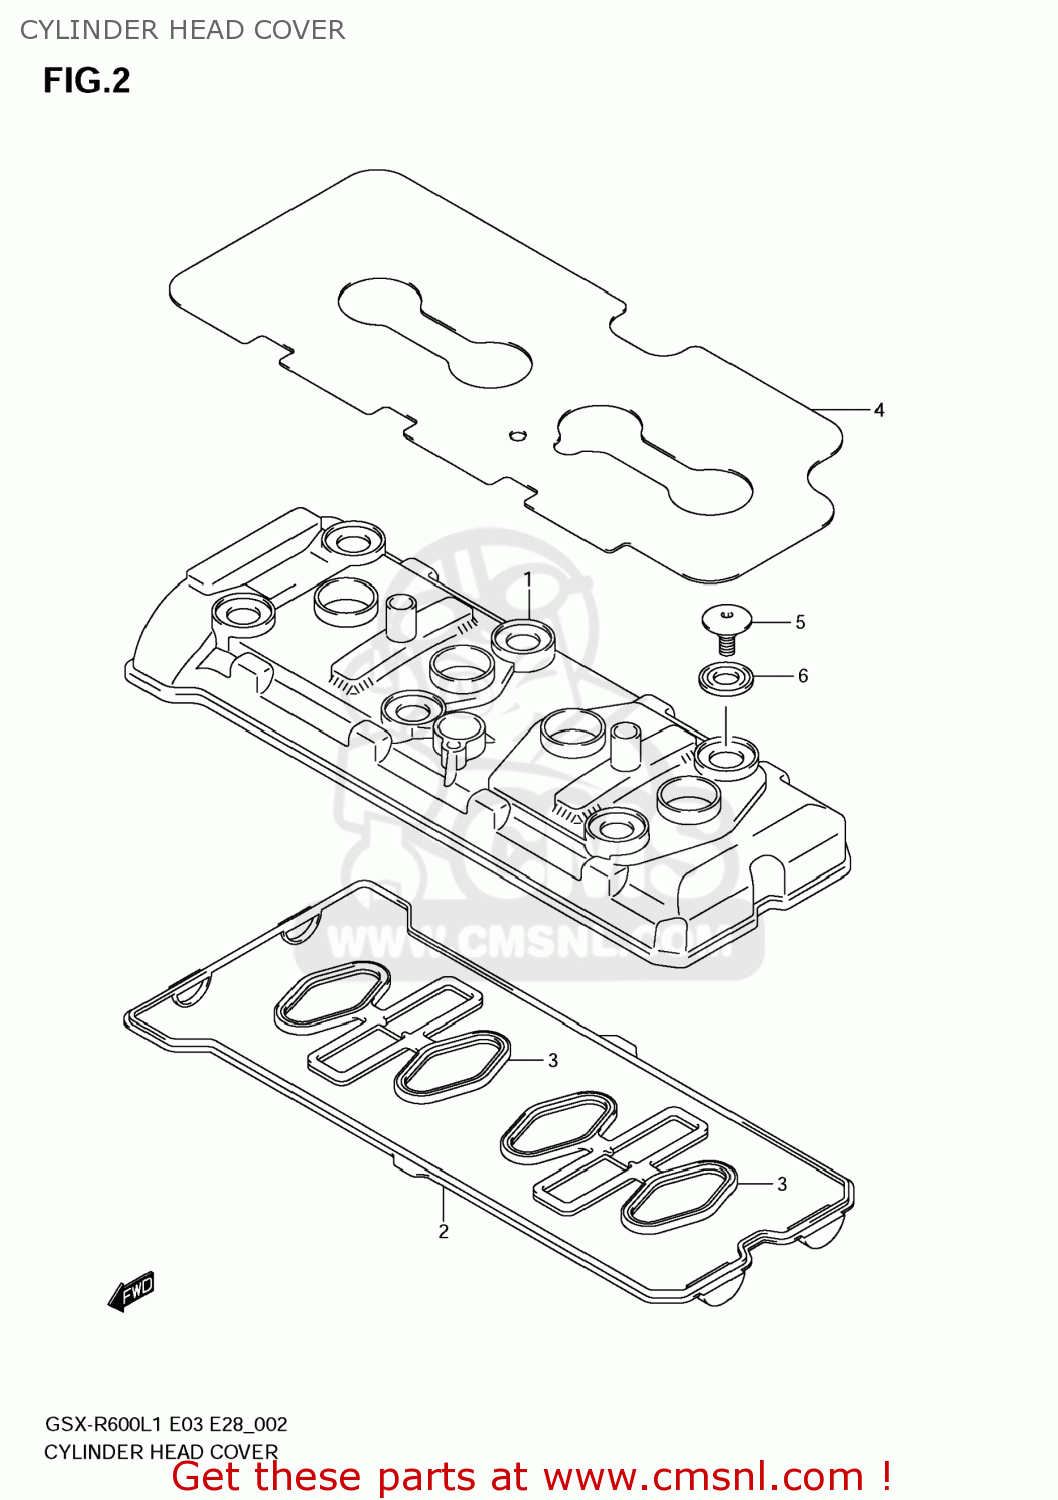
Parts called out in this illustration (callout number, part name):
1	COVER,CYLINDER HEAD
2	GASKET,CYL HEAD COVER NO.1 (NAS)
3	GASKET,CYL HEAD COVER NO.2 (NAS)
4	SHIELD,CYLINDER HEAD COVER
5	BOLT(7X17.5)
6	WASHER,CYL HEAD COVER
